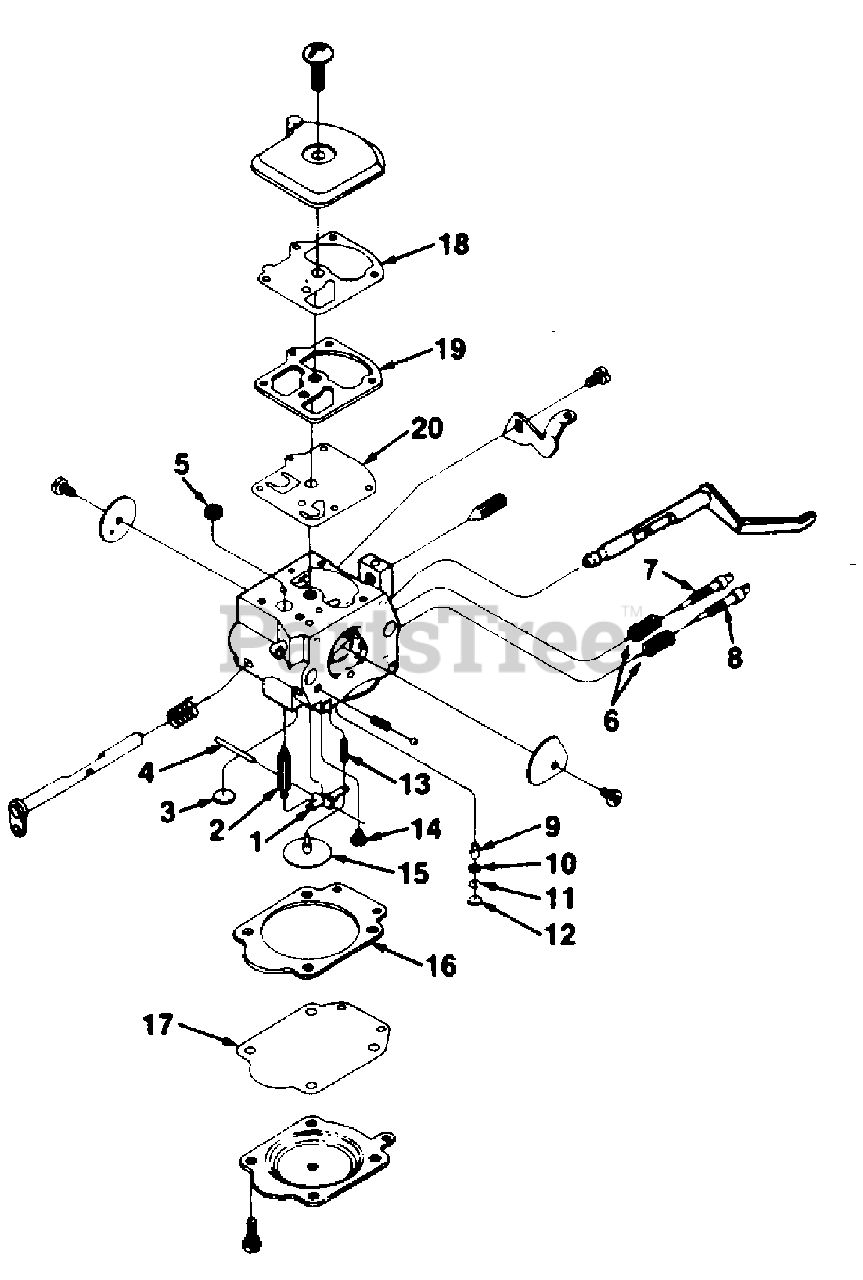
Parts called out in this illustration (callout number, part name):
1	Repair Kit
2	Repair Kit
3	Repair Kit
4	Repair Kit
5	Repair Kit
6	Repair Kit
7	Repair Kit
8	Repair Kit
9	Repair Kit
10	Repair Kit
11	Repair Kit
12	Repair Kit
13	Repair Kit
14	Repair Kit
15	Repair Kit
16	Repair Kit
